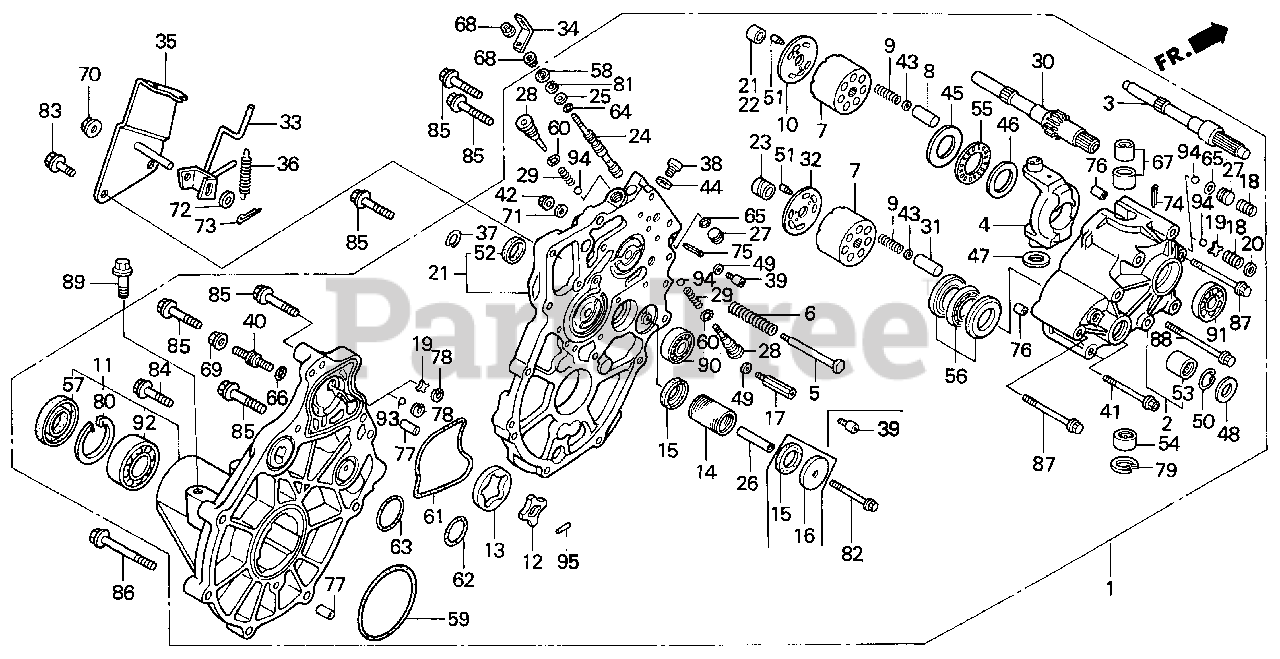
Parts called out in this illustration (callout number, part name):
1	TRANSMISSION SUB-ASSY. (H.S.T.)
2	CASE, PUMP
3	SHAFT, PUMP
4	BOWL, PUMP CONTROL
5	SHAFT, RETURN
6	SPRING, RETURN
7	CYLINDER, PUMP
8	PISTON, PUMP
9	SPRING, PISTON
10	PLATE, PUMP CYLINDER
11	CASE, CHARGE PUMP
12	ROTOR, TROCHOID
13	VANE, TROCHOID
14	FILTER, SUCTION
15	CAP, FILTER GUIDE
17	VALVE ASSY., RELIEF
18	SPRING, RELIEF VALVE
21	PLATE, DISTRIBUTOR
22	BUSH, PUMP SHAFT
23	BUSH, MOTOR SHAFT
24	SPOOL, NEUTRAL VALVE
25	COLLAR, NEUTRAL VALVE
26	COLLAR, FILTER SETTING
27	CAP, NEUTRAL VALVE
28	BOLT, CHECK VALVE
29	SPRING, CHECK VALVE
30	SHAFT, MOTOR
31	PISTON, MOTOR
32	PLATE, MOTOR CYLINDER
33	LEVER, NEUTRAL VALVE
34	PLATE, NEUTRAL VALVE
35	BRACKET, NEUTRAL LEVER
36	SPRING, NEUTRAL VALVE LEVER
37	RING, PISTON STOPPER
38	BOLT, SPECIAL (10X13)
39	BOLT, SPECIAL (8X9)
40	BOLT, ADJUSTING (6X33)
41	BOLT, FLANGE (8X73)
42	NUT, U (6MM)
43	WASHER, PISTON (5MM)
44	WASHER, SEALING (10MM)
45	BEARING, PLATE
46	PLATE, NEEDLE BEARING
47	WASHER (20.5X32X3)
48	WASHER, THRUST (17.5MM)
49	WASHER, SEALING (8MM)
50	CLIP, BEARING
51	PIN, DOWEL (4X3)
52	PLUG, SEAL (31X6)
53	BEARING, NEEDLE (17X24X15)
54	BEARING, NEEDLE (20MM)
55	BEARING, THRUST ROLLER
56	BEARING, THRUST BALL
57	OIL SEAL (25X52X7)
58	DUST SEAL (5X14X3)
59	O-RING (3X70)
60	O-RING (11.8X2.4)
61	O-RING (2.4)
62	O-RING (22.5X2.4)
63	O-RING (34X2.4)
64	O-RING (6.8X1.9) (P7)
65	O-RING (P9)
66	O-RING (4.8X1.9)
67	COLLAR, CONTROL BOWL
68	NUT, FLANGE (5MM)
69	NUT, FLANGE (6MM)
70	NUT, FLANGE (8MM)
71	WASHER, PLAIN (6MM)
72	WASHER, PLAIN (6MM)
73	PIN, COTTER (2.0X12)
74	PIN, COTTER (3.0X45)
75	PIN, COTTER (4.0X30)
76	PIN A, DOWEL (6X10)
77	PIN A, DOWEL (8X14)
78	CIRCLIP (INNER) (12MM)
79	CIRCLIP (INNER) (28MM)
80	CIRCLIP (INNER) (52MM)
81	CIRCLIP (INNER) (14MM)
82	BOLT, FLANGE (6X75)
83	BOLT, FLANGE (8X10)
84	BOLT, FLANGE (8X35)
85	BOLT, FLANGE (8X40)
86	BOLT, FLANGE (8X65)
87	BOLT, FLANGE (8X80)
88	BOLT, FLANGE (8X95)
89	BOLT, FLANGE (10X25)
90	BEARING, RADIAL BALL (6004)
91	BEARING, RADIAL BALL (6203)
92	BEARING, RADIAL BALL (6205)
93	BALL, STEEL (#10) (5/16)
94	BALL, STEEL (#13) (13/32)
95	ROLLER (3X16.8)
